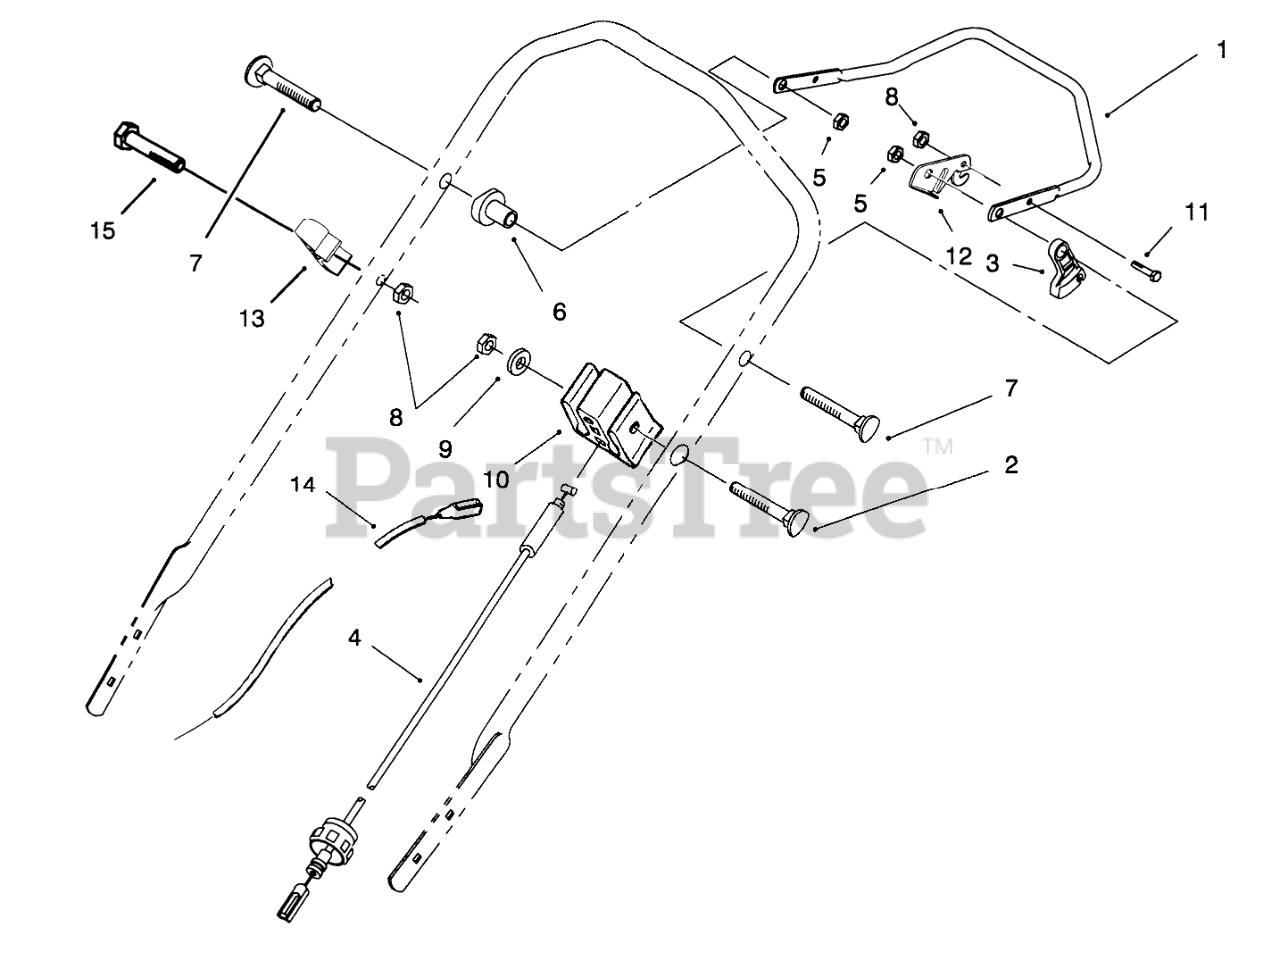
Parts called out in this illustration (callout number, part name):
1	Bar-Control
2	HANDLE SCREW
3	LEVER-TRACTION
4	CABLE-TRACTION
5	NUT-LOCK, NI
6	SPACER-SUPPORT
7	5/16-18 X 2 HNDLE SCREW
8	NUT-LOCK, NI
9	WASHER-FLAT
10	SUPPORT-CABLE
11	SCREW-HH
12	LEVER-CONTROL
13	Guide-Rope
14	BRAKE CONTROL
15	.250-20X1.625 HH SCREW
